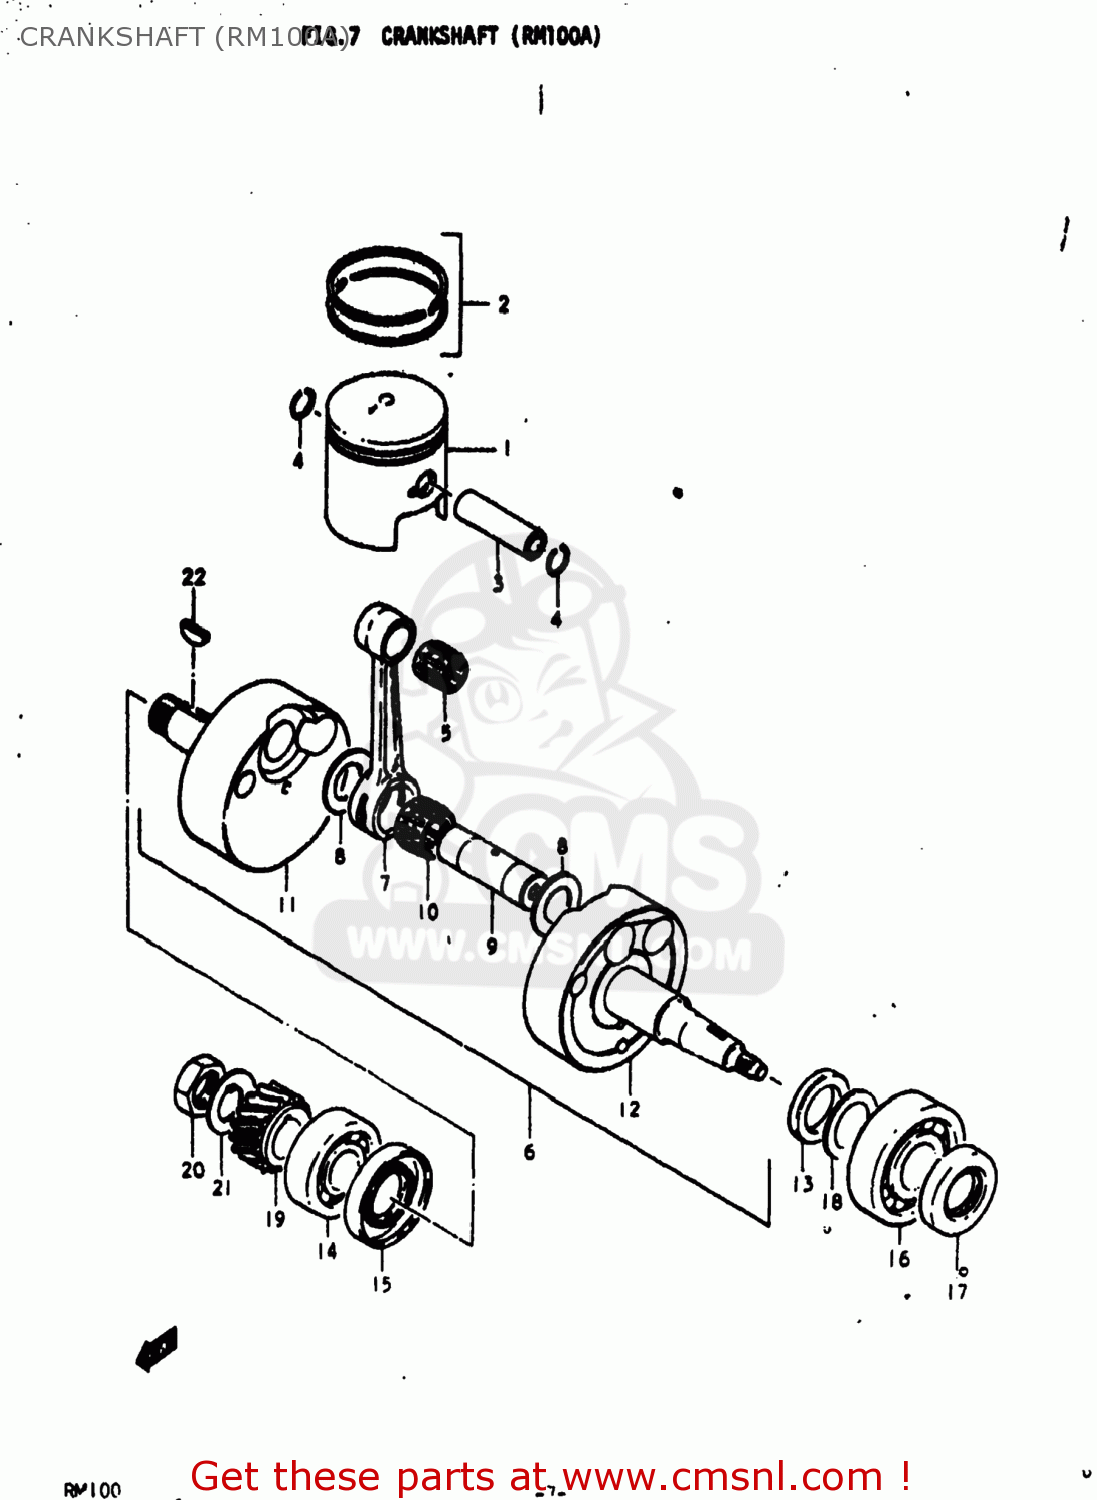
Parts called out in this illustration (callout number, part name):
1	PISTON
2	RING SET,PISTON
3	PIN,PISTON 14MM
4	RING,SNAP 14MM
5	BEARING
6	CRANKSHAFT ASSEMBLY
7	CONNECTING ROD
8	WASHER(19X32X1)
9	PIN,CRANK
10	BEARING
11	CRANKSHAFT
12	CRANKSHAFT,LEFT
13	SPACER
14	BEARING
15	SEAL,OIL(26X52X8)
16	BEARING(25X62X17)
17	OIL SEAL
18	SHIM(25X36X0.8)
19	GEAR,PRIMARY DRIVE
20	NUT
21	WASHER
22	KEY
